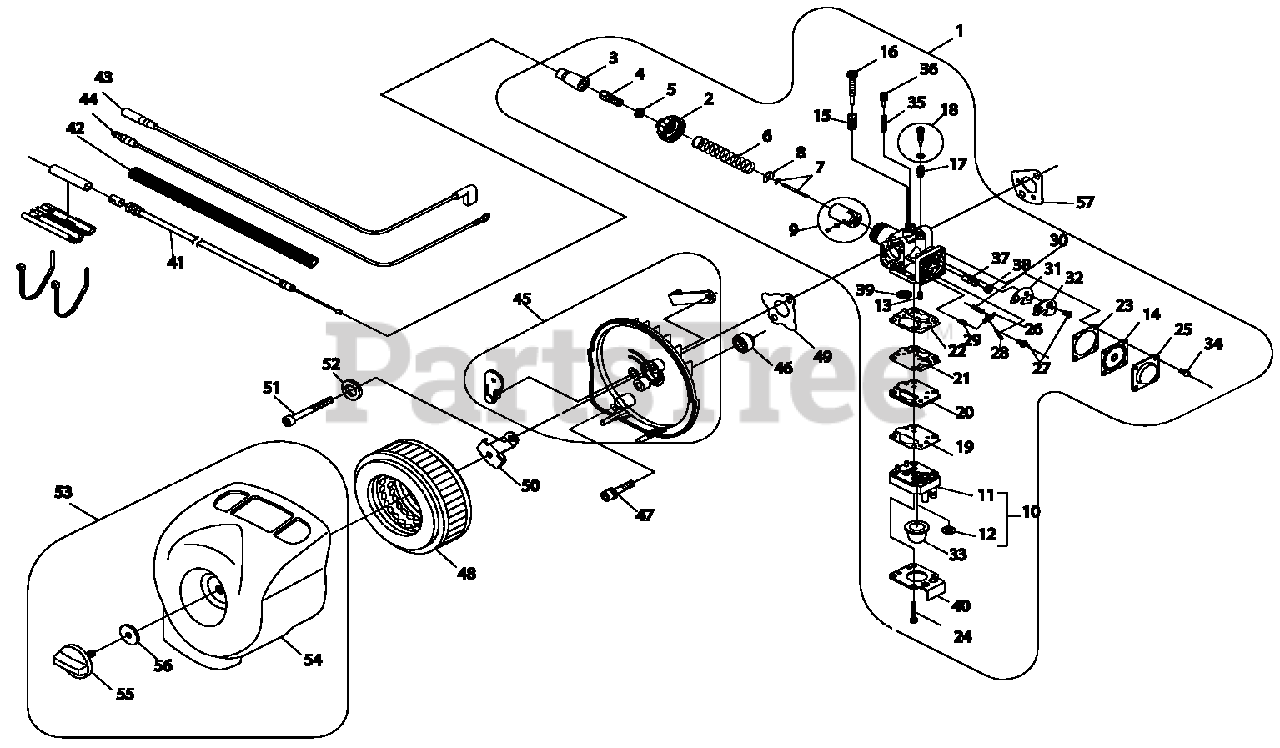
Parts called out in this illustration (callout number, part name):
1	CARBURETOR
2	COVER - TOP
3	CAP, DUST
4	NUT, CABLE ADJUST
5	LOCKNUT
6	SPRING, THROTTLE
7	NEEDLE, JET
8	WASHER
9	SLIDE VALVE
10	PUMP COVER ASSY
11	COVER, PUMP
12	VALVE
13	SPRING
14	DIAPHRAGM, METERING
15	SPRING, ADJUST
16	NEEDLE - HIGH SPEED
17	SPRING
18	SCREW, IDLE ADJUST
19	GASKET, PUMP
20	PLATE, PUMP
21	DIAPHRAGM, PUMP
22	GASKET, PUMP
23	GASKET
24	SCREW
25	COVER, DIAPHRAGM
26	LEVER, METERING
27	SCREW, METERING LEVER PIN
28	PIN, METERING LEVER
29	VALVE, NEEDLE
30	SPRING
31	GASKET
32	PLATE
33	BULB, PURGE
34	SCREW
35	SPRING
36	SCREW, SLOW AIR
37	NEEDLE, JET
38	HOLDER, JET
39	SCREEN, SPARK ARRESTOR
40	PLATE, PUMP
41	CABLE, THROTTLE
42	TUBE
43	LEAD - IGNITION
44	LEAD - GROUND
45	AIR FILTER CASE ASSY
46	INSULATOR
47	SCREW - 5X40
48	FILTER, AIR
49	GASKET, INTAKE
50	PLATE
51	SCREW - 5X75
52	LOCKWASHER - 5
53	AIR FILTER COVER ASSY
54	COVER, AIR FILTER
55	THUMBSCREW
56	WASHER
57	GASKET, INTAKE
